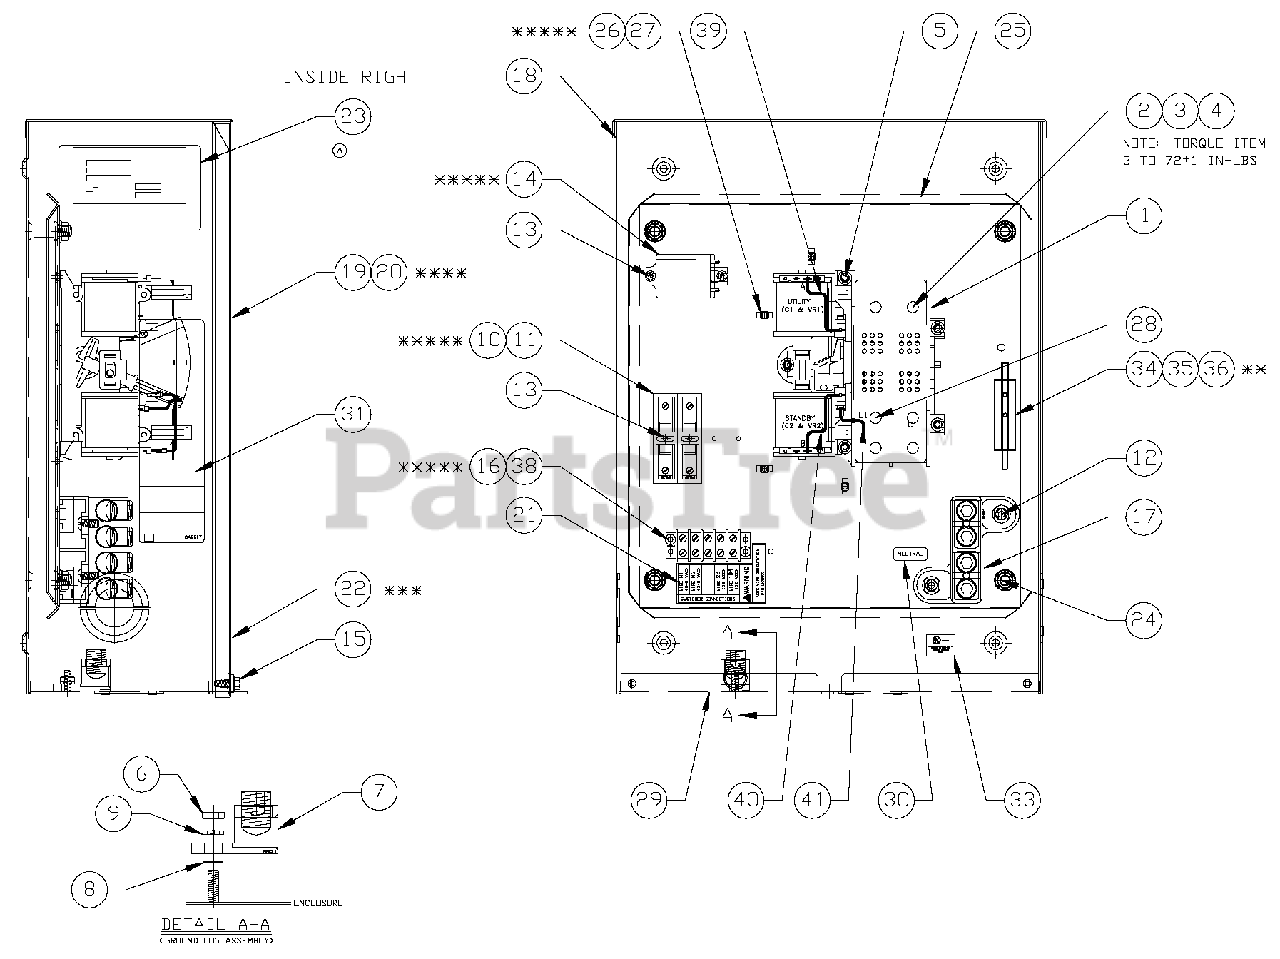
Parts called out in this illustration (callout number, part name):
1	TR SW-HSB 200A 2P 250V
2	LUG SLDLSS 250-#6 AL/CU
3	SCREW BHSC 1/4-20 X 3/8
4	WASHER LOCK M6-1/4
5	SCREW HHTT M5-0.8 X 10 BP
6	NUT HEX M8-1.25 G8 YEL CHR
7	LUG SLDLSS 350-#6 X 13/32 AL/CU
8	WASHER SHAKEPROOF EXT 5/16 STL
9	WASHER LOCK M8-5/16
10	FUSE 5A X BUSS
11	FUSE HOLDER
12	SCREW HHTT M6-1.0 X 12 ZINC
13	SCREW HHTT M4-0.7 X 10 BP
14	RELAY PNL 12VDC DPDT 10A@240VA
15	SCREW TH-FRM M6-1 X 16 N WA Z/JS
16	RIVET POP .156 X .675 AL
17	ASS'Y-NTRL BL150-200A
18	WELDMENT XFER SW BOX HSB
19	COVER TRANSFER SWITCH BOX HSB
21	DECAL TERMINAL STRIP
22	DECAL-LIVE CIRCUIT
23	DECAL SWITCH RATING
24	NUT LOCK FL 3/8-16
25	SUBPLT TRANSFER SWITCH HSB
26	HOLDER CABLE TIE
27	TIE WRAP UL 3.9" X .10" NATL
28	90 DEGREE DN SPADE CONNECTOR
29	DECAL GROUND LUG
30	DECAL NEUTRAL
31	DECAL MANUAL 5A FUSE
33	DECAL-UL LIST HSB
34	BRACKET ARM EXTENDER
35	SCREW HWHS #6-25 X 3/8 ZNC
36	ARM EXTENDER PIN
38	BLOCK TERM 20A 5 X 6 X 1100V
41	WIRE E1
